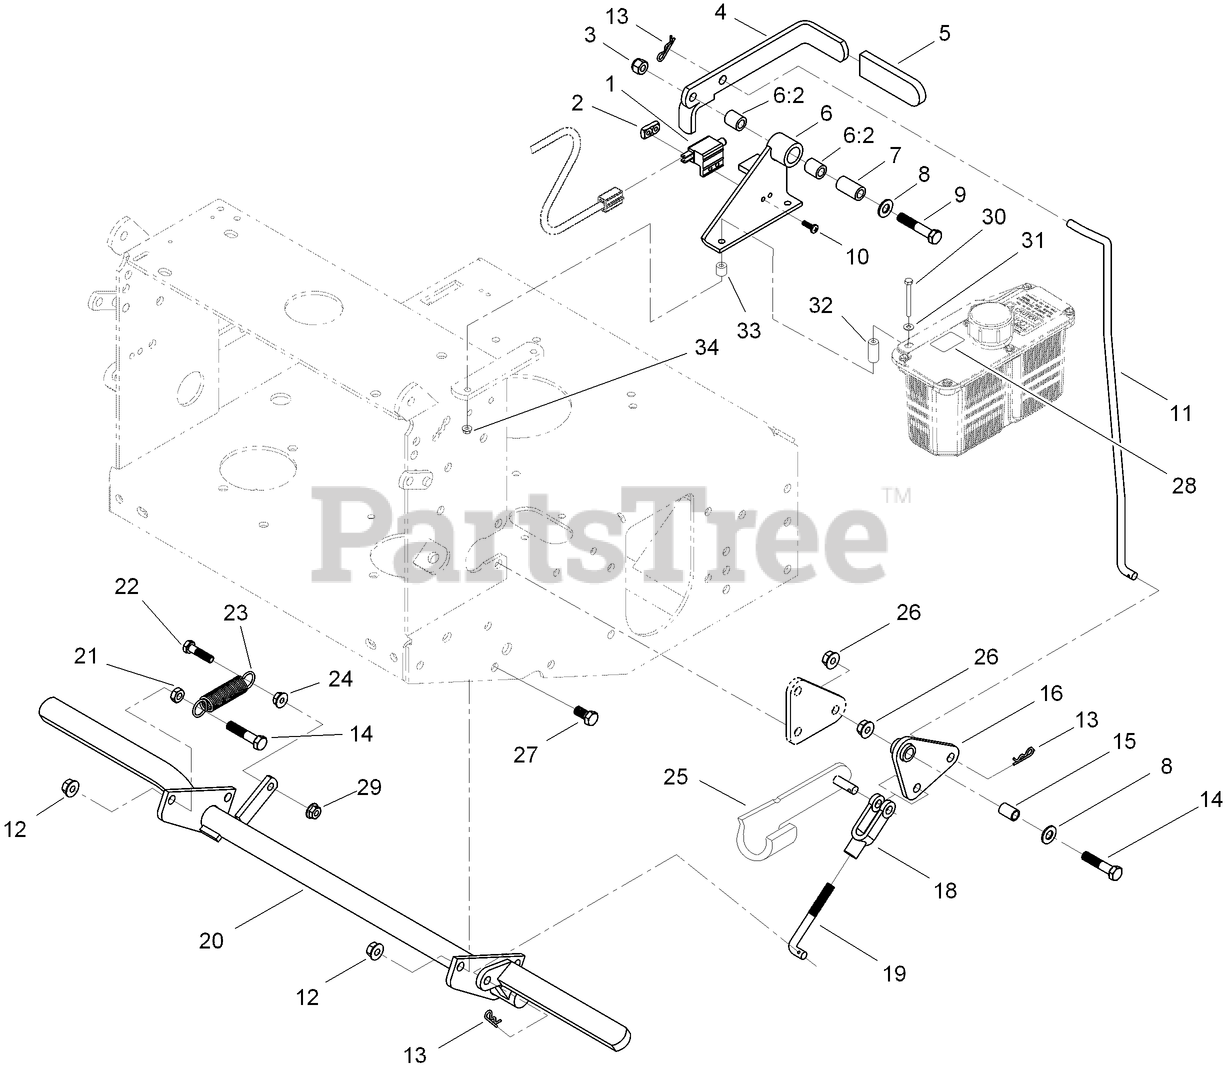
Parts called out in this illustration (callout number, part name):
1	SWITCH-OPEN, NORMALLY
2	PLATE-TAPPED
3	NUT-LOCK, NI
4	Lever-Parkbrake
5	GRIP-LEVER
6	Bracket ASM
6:2	SLEEVE-BUSHING
7	Bushing-Pivot
8	WASHER-FLAT
9	SCREW-HH
10	SCREW-PPH
11	Linkage-Upper
12	NUT-LOCK, NI
13	PIN-COTTER
14	SCREW-HH
15	Bushing-Plastic
16	Bellcrank ASM
18	YOKE-LINKAGE, BRAKE
19	Linkage-Lower
20	BRAKE ASM
21	NUT-JAM
22	SCREW-HH
23	SPRING-IDLER
24	NUT-HF
25	Pin-Spring, Clevis
26	NUT-HF
27	SCREW-HH
28	DECAL-BRAKE, PARK
29	NUT-LOCK, NI
30	SCREW-HH
31	WASHER-FLAT
32	Spacer
33	SPACER
34	NUT-HF
